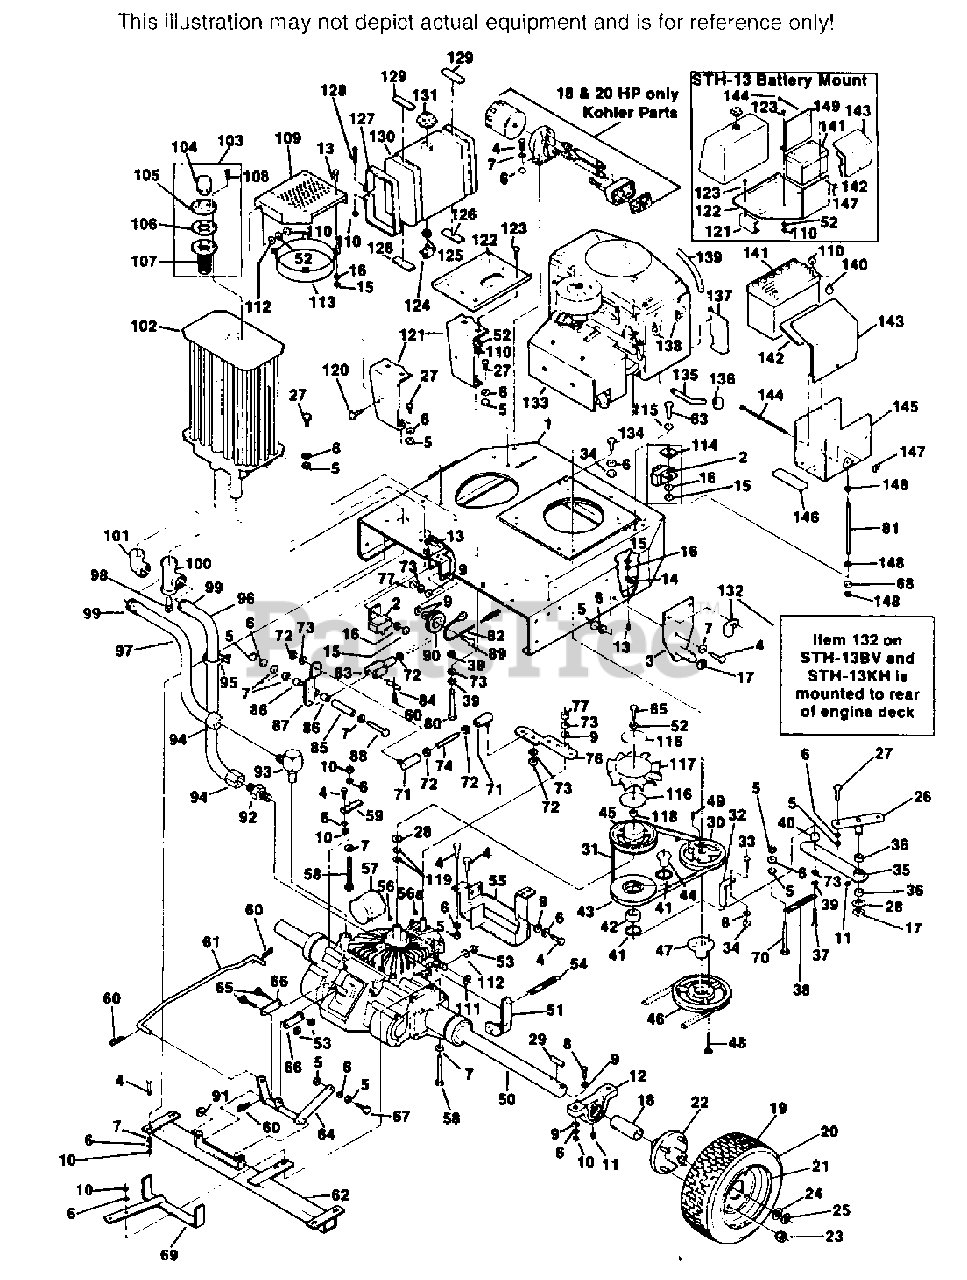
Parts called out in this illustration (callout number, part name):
1	ENGINE DECK
3	HITCH BRACKET
6	LOCK WASHER, 5/16 SPRING
9	FLAT WASHER, 3/8(25/64 X 15/16 X 12 GA.)
11	GREASE FITTING
12	BEARING, PILLOW BLOCK 1"
14	CLIP, CABLE
17	RETAINING RING, 3/4" "E"
18	SPACER, DRIVE AXLE
19	WHEEL ASSY. COMPLETE(INCL., 20-23)
20	TIRE, 16 X 6.50-8, 2 PLY
21	RIM
22	HUB AND FLANGE(INCL. BOLT & NUT)
23	BOLT AND NUT
24	FLAT WASHER, 1.062 X 1 1/2 X 18 GA.
25	RETAINING RING, 1" "E"
26	PIVOT BASE, IDLER
28	FLAT WASHER, 49/64 X 1 1/4 X .035
29	KEY, 1/4 X 1/4 X 2 1/2
30	PULLEY, ENGINE TRANSAXLE DRIVE
31	BELT, TRANSAXLE DRIVE
34	HEX NUT, ELASTIC STOP LOCK 5/16-18
35	IDLER ARM, TRANSMISSION(INCL.(2) 36 &(1)
36	BRONZE BUSHINGS
38	SPRING, TRANSMISSION IDLER
40	SPACER, IDLER
41	RETAINING RING, 1 9/16 INTERNAL
42	BEARING, IDLER PULLEY
43	PULLEY, TRANSAXLE IDLER
44	SLEEVE, IDLER TAPPED
45	PULLEY, TRANSAXLE DRIVE
46	PULLEY, ENGINE BLADE DRIVE(INCL. 47, 48)
47	HUB, TAPERED
49	KEY, 1/4 X 1/4 X 2 1/2 PLATED
50	TRANSAXLE, EATON
51	CONTROL ARM, DUMP VALVE
52	LOCK WASHER, 1/4 SPRING
53	HEX NUT, ELASTIC STOP LOCK 1/4-20
54	SPRING, RETURN
55	PROTECTOR, TRANSAXLE
56	KEY, WOODRUFF #61, 3/16 X 5/8
56A	KEY, WOODRUFF #3, 1/8 X 1/2
57	FILTER, EATON 10 MICRON
59	SPACER, TRANSAXLE
60	HAIR PIN COTTER, SMALL
61	BRAKE ROD
62	SUPPORT, TRANSAXLE
64	BELLCRANK, BRAKE SHAFT
66	LINK, BRAKE
68	LOCK WASHER, 7/16 SPRING
69	BELT GUIDE, BLADE DRIVE
71	BALL JOINT
73	LOCK WASHER, 3/8 SPRING
74	CONNECTOR ROD
76	CONTROL ARM
81	ROD, BATTERY SUPPORT
82	SPRING/CABLE ASSY.
83	CLEVIS, HYDRO CONTROL
84	CLEVIS PIN
85	SLEEVE, CONTROL ARM BELLCRANK
86	BRONZE BUSHING
87	BELLCRANK, CONTROL ARM
90	PULLEY, SPRING/CABLE
91	1/2" FLAT WASHER
92	ADAPTER, 37' FLARE
93	ELBOW, O-RING SEAL ADAPTER
94	COUPLING 37' FLARE
95	CABLE TIE
96	HOSE, LONG
97	HOSE, SHORT
98	PIPE PLUG, 1/2 NPT
99	COUPLING 1/2 NPT
100	TEE, 1/2 NPT
101	ELBOW 90' 1/2 NPT
102	OIL RESOVOIR
103	FILER CAP AND MOUNTING ASSY.(INCL. 104-107)
104	CAP
105	SEAL RING
106	GASKET
107	BASKET
109	FAN SHIELD
111	FLAT WASHER, .594 X 1.125 X .063
113	FAN SHROUD
114	STOP, MOWER ENGAGE
116	FLAT WASHER, 3/8 X 2 X 16 GA.
117	FAN, HYDRO
118	SPACER, FAN
119	FLAT WASHER, 49/64 X 1 1/4 X 16 GA.
121	BRACKET, FUEL TANK AND BATTERY
122	PLATE, FUEL TANK AND BATTERY MTG.
124	FUEL SHUT-OFF VALVE
125	BUSHING, FUEL TANK/VALVE
126	PAD, TANK SUPPORT
127	STRAP, FUEL TANK
129	PAD, STRAP CUSHION
130	FUEL TANK ASSY.(INCLS TANK, 124, 125, 131)
131	FUEL TANK CAP
132	CLIP, BATTERY OVERFLOW TUBE
133	SWITCH, INTERLOCK
135	OIL DRAIN EXTENSION
136	PIPE CAP, 3/8 HEX
141	BATTERY
142	INSULATION, BATTERY COVER
143	BATTERY COVER
146	PAD, BATTERY SUPPORT
147	WING NUT, ESNA SELF LOCK 1/4-20
149	BATTERY CLAMP
